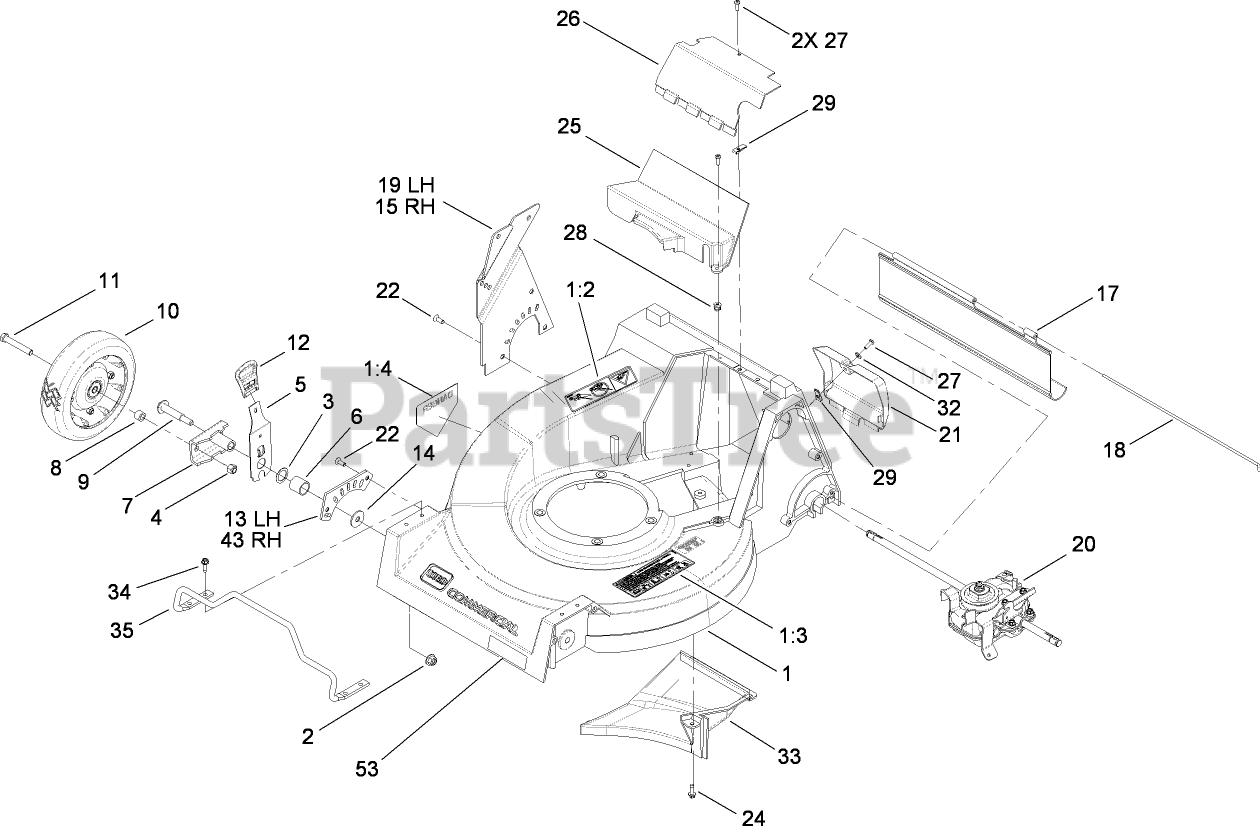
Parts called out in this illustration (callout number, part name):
1	DECK ASM
1:2	DECAL-DANGER
1:3	DECAL-WARNING
1:4	DECAL-DANGER
2	NUT-LOCK
3	WASHER
4	NUT-LOCK, CONE
5	FRONT SPRING ARM ASM
6	SPACER-BEARING
7	ARM-PIVOT, FRONT
8	SPACER-WHEEL
9	SCREW-SHOULDER
11	SCREW-HH
12	KNOB-HOC
13	PLATE-FRONT HOC, LH
14	WASHER
15	PLATE-REAR HOC, RH
17	SHEILD-TRAILING
18	ROD-SHIELD
20	GEAR CASE ASM
21	DOOR-ACCESS, REAR
22	SCREW-HH
24	SCREW-HWHTF
25	COVER-BELT, LOWER
26	COVER-BELT, UPPER
28	NUT-CLIP
29	NUT-TYPE J
32	WASHER-FLAT
33	BAFFLE-CHUTE, FLOOR
34	SCREW-HWHTF
35	GUARD-ENGINE
43	PLATE-FRONT HOC, RIGHT
53	DECAL-BLADE
